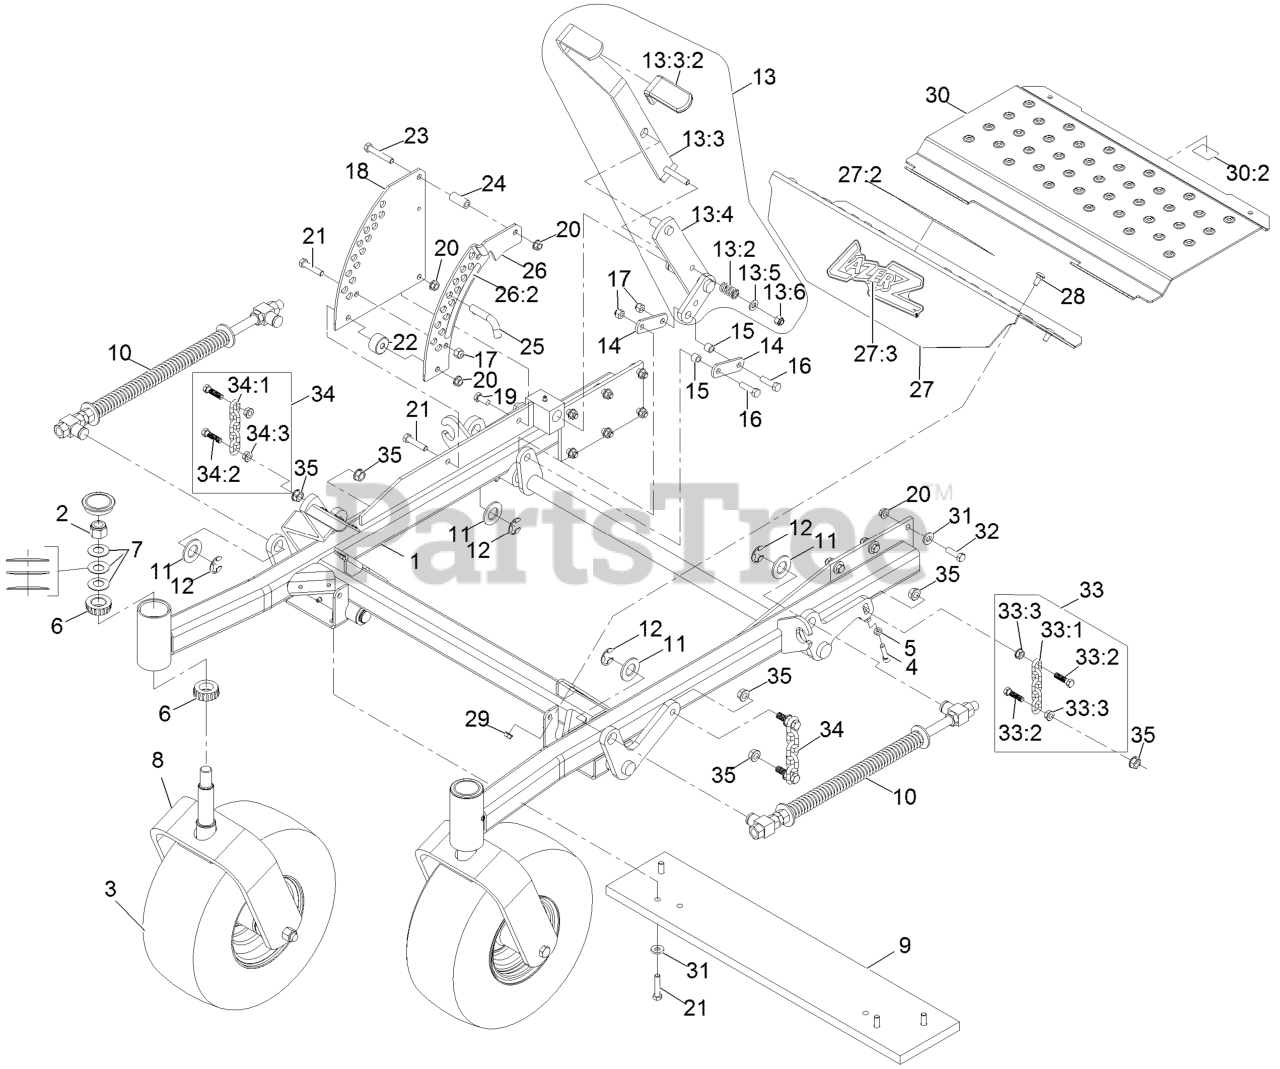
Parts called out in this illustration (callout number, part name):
1	ASM-Frt Frm 60Rd
2	NUT-LOCK, NI
3	ASM-WHL AND TIRE
4	SCREW-HSH
5	NUT-JAM
6	Cone-Bearing Tapered Roller
7	WASHER-BELLVILLE
8	WLD-CASTER FORK 15
9	BAR,WEIGHT 38.1#
10	FRONT FRAME SPRING ASM
11	WASHER-FLAT
12	RING-RETAINING, EXT
13	ASM,Deck Lift Handle
13:2	SPRING-COMPRESSION
13:3	LIFT LEVER/GRIP ASM
13:3:2	GRIP-LEVER, LIFT
13:4	WLD,ARM DECK LIFT
13:5	WASHER-FLAT
13:6	NUT-LOCK, NI
14	ARM-LIFT, DECK
15	BUSHING
16	SCREW-HH
17	NUT-LOCK, NI
18	PLATE-DECK LIFT NOTCHED O
19	SCREW-HH
20	NUT-HHF, WHIZ
21	SCREW-HH
22	Stop, Deck Height
23	SCREW-HH
24	BUSHING-LEVER, LIFT
25	PIN-HOC
26	PLATE-LIFT, DECK W/DECAL
26:2	DECAL-HEIGHT, DECK
27	ASM, FLOORPAN FRONT W/DEC
27:2	DECAL,LAZER MODEL
27:3	DECAL-SLOPE
28	BOLT-CARR
30	ASM, FLOORPAN LIFTOUT W/D
30:2	DECAL-GUARD
31	WASHER-BELLEVILLE
32	SCREW-HH
33	DECK CHAIN ASM
33:1	CHAIN-LIFT, DECK
33:2	SCREW-HH
34	DECK CHAIN ASM
34:1	CHAIN-LIFT, DECK
34:2	SCREW-HH
